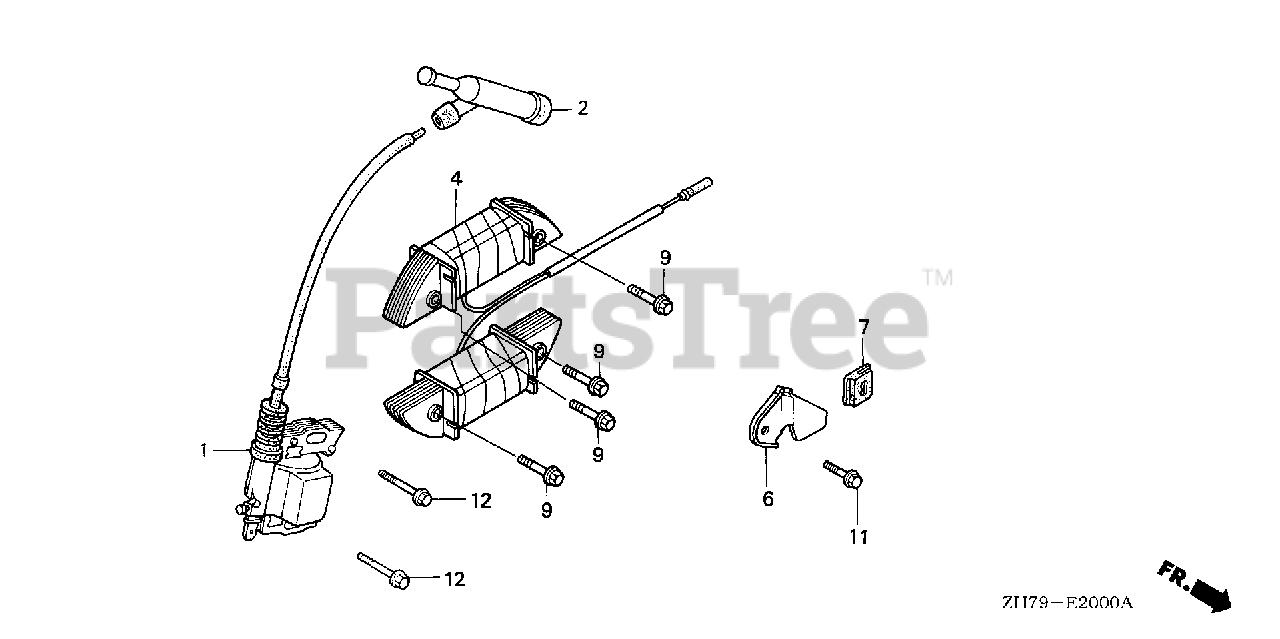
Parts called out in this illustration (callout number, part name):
1	COIL ASSY., IGNITION
2	CAP ASSY., NOISE SUPPRESSOR
12	BOLT, FLANGE (6X25)
